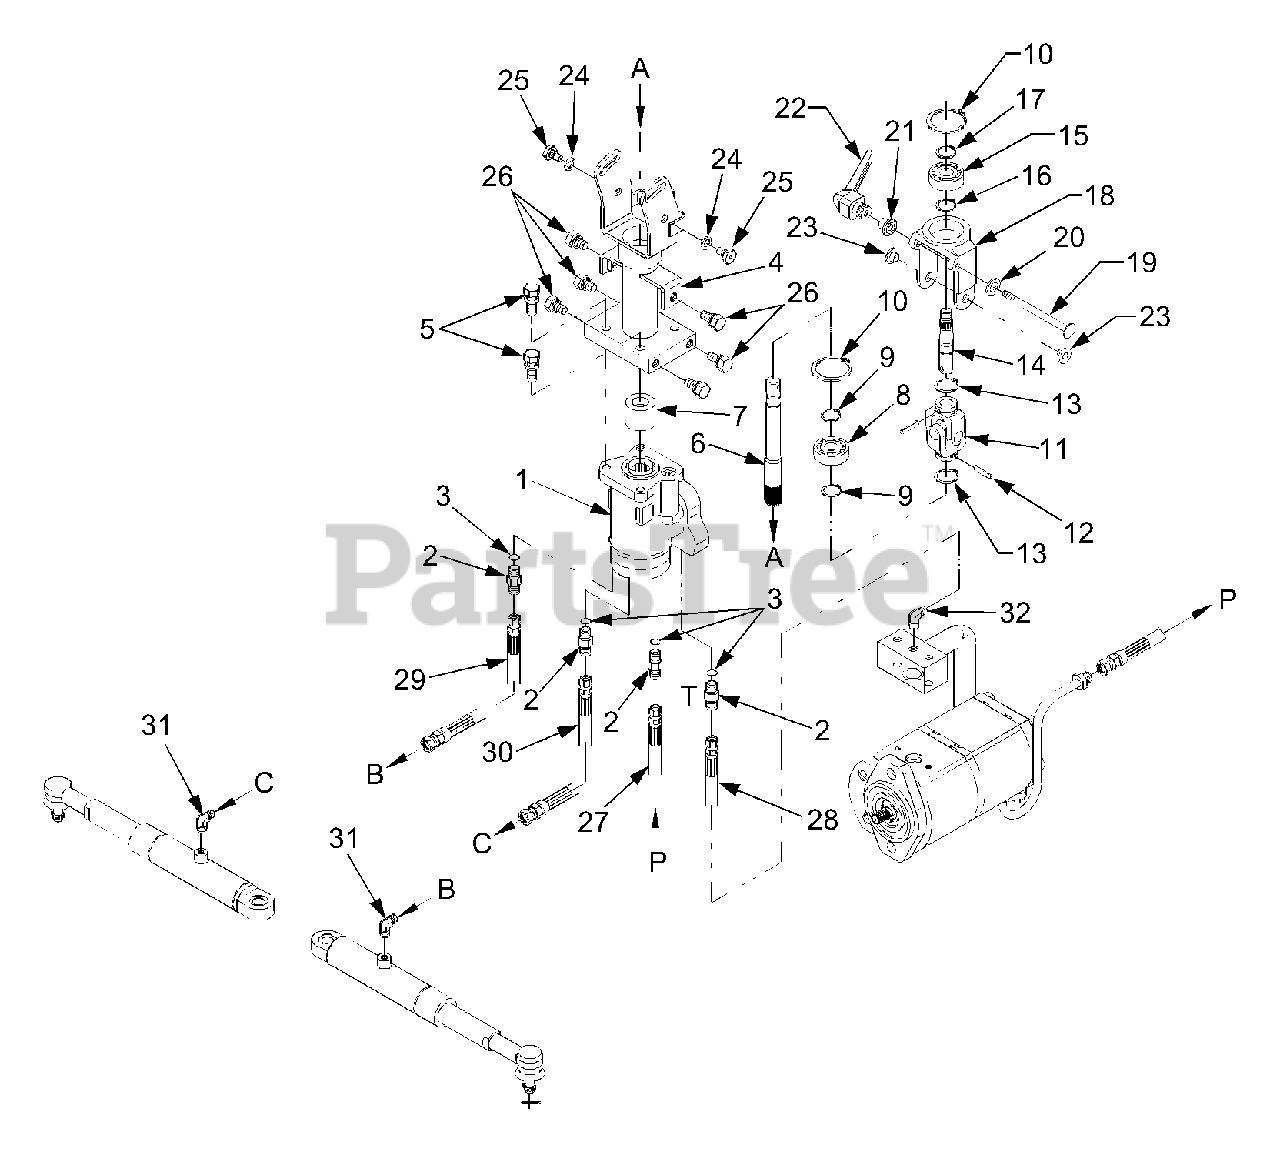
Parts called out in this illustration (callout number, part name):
1	Unit, Power Steering
6	Shaft, Steering
8	Bearing, Ball
11	Joint, Universal
14	Shaft, Connector
15	Bearing, Ball
20	Washer 1, Holding
21	Washer 2, Holding
24	Washer, Spring
27	Steering Hose (P) Ass'y
28	Steering Hose (T) Ass'y
29	Steering Hose (L) Ass'y
30	Steering Hose (R) Ass'y
32	Adapter 1,cylinder
